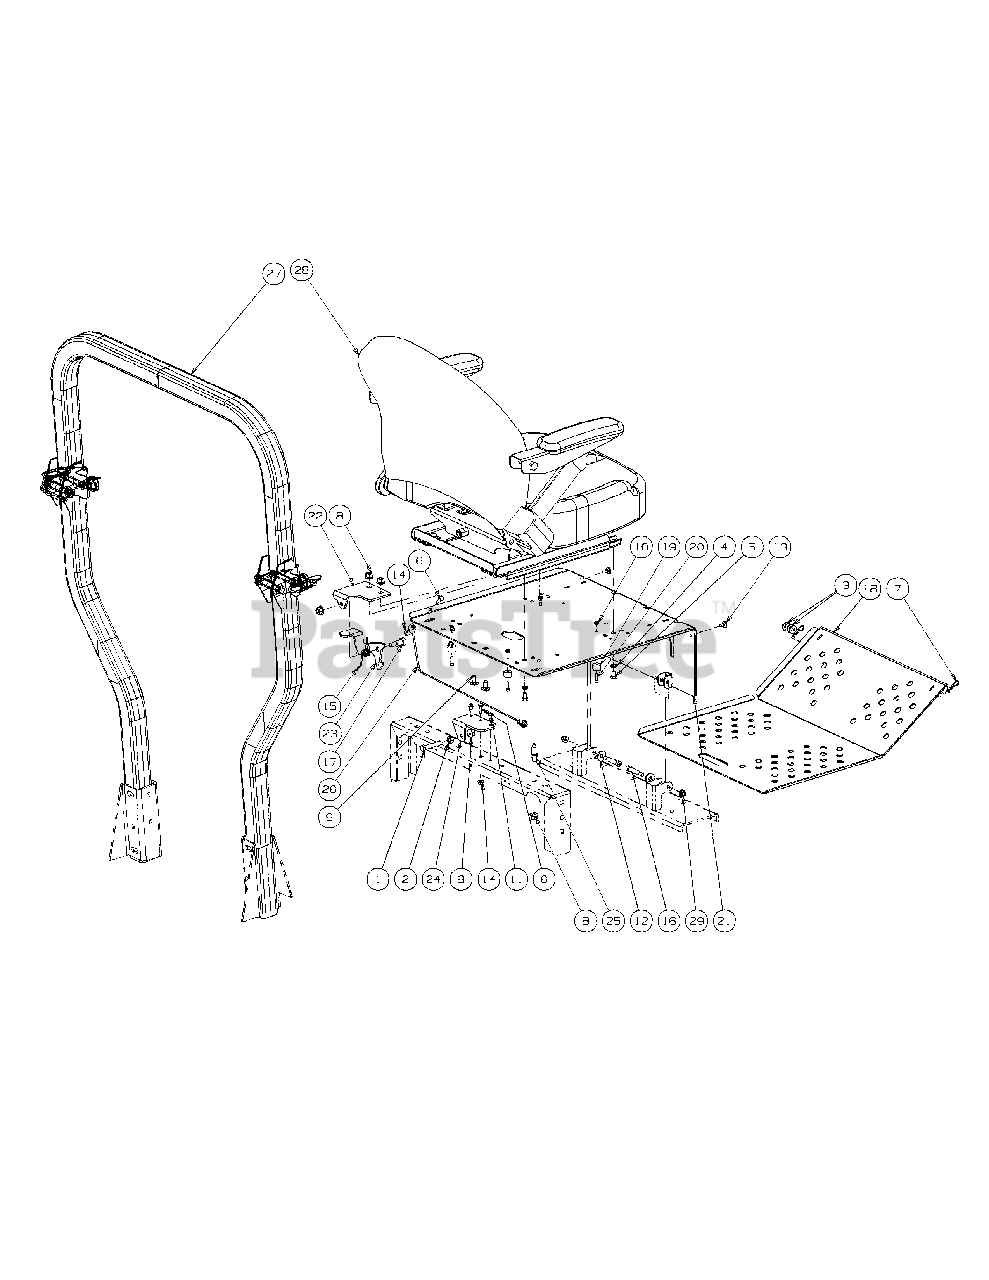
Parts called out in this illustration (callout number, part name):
1	Hex Cap Screw 3/8-16 x 2.00
2	Hex Nut, 3/8-16
4	Lock Washer, 5/16
5	Hex Cap Screw, 5/16-18 x 1/2
6	Screw, Hex, Cap, 1/4-20 x .75
7	Hair Pin, 3/8-1/2
8	Flange Lock, Hex Nut, 3/8-16
9	Carriage Bolt, 3/8-16 x .75 Long
10	Nut, #10-24, Nylon Lock
11	Screw, TT, 1/4-20, 0.5, Hex Index Washer
12	Flat Washer, .406 ID, 1.0 OD, .105
13	Rubber Bumper, .62 OD x .22 Thick
14	Lock Nut, 1/4-20
15	Deck Lift Spring, Left Hand
16	Shoulder Bolt, .375 x 1.50
17	Shoulder Bolt, 1/2 x 3/4, 3/8-16
18	Floor Panel Assembly
19	Rubber Stop with Washer
20	Standard Cap Screw, #10-24 x .75
21	Seat Plate Assembly
22	Seat Latch Bracket
23	Latch Lever Bracket
24	Latch Bracket
25	Adjustable Stud
26	Cable Support
27	Foldable Rops Assembly includes:
27	Pin, Lock
28	Seat w/ Seat Belt & Suspension
28	Armrest Kit
28	Seat Back Cover
28	Seat Bottom Cover
28	Seat Switch Assembly
29	Flange Lock Nut, 5/16-18
